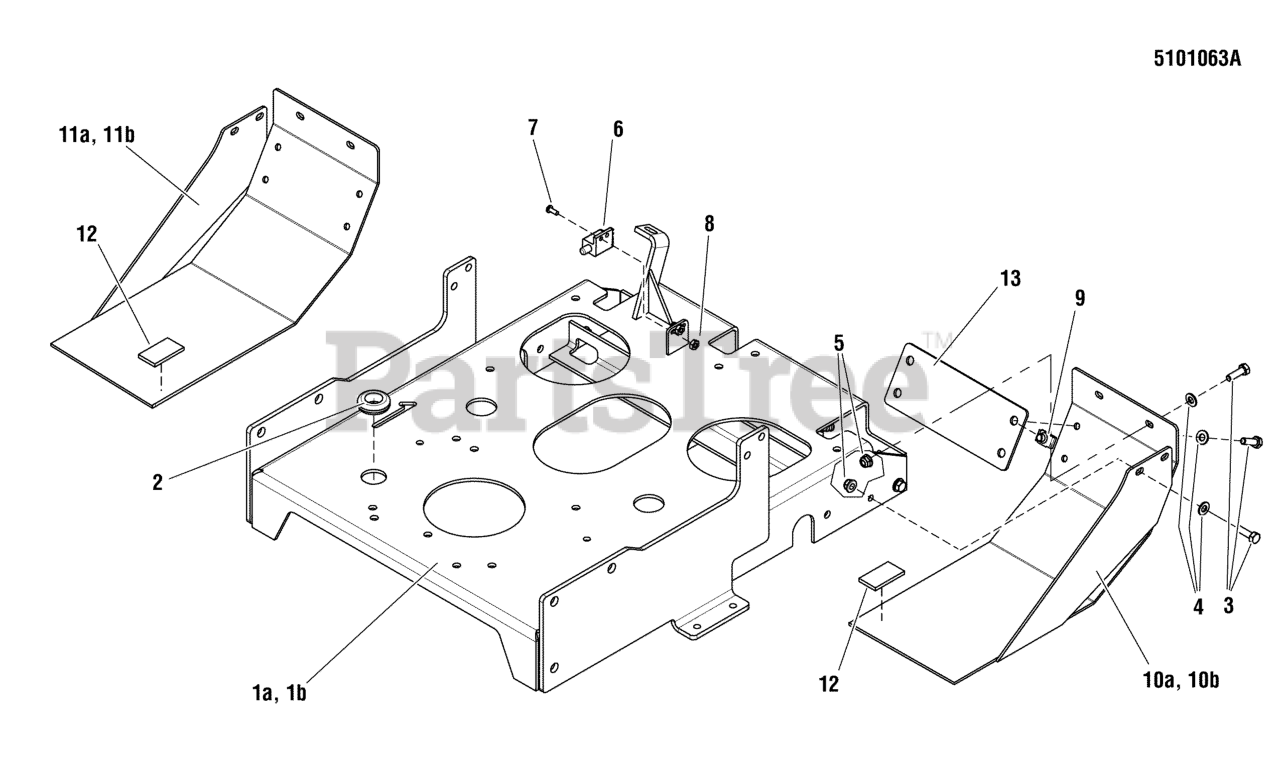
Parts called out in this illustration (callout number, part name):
2	GROMMET, 7/8
3	BOLT, 5/16-18 X 1 GD5 YZ
4	WASHER, 5/16" SAE
5	NUT, 5/16-18 HEX NYLOCK FLANGE
6	SWITCH, PLUNGER, N.C.
7	SCREW- #10-24 X 1/2 ROUND PHILLIPS
8	NUT, #10-24 HEX
9	BODY CLIP, 5/16-18-7GA MATERIAL
12	PAD, RUBBER MOUNT, 1/4 MAT
13	PLATE, REAR GUARD - RED
